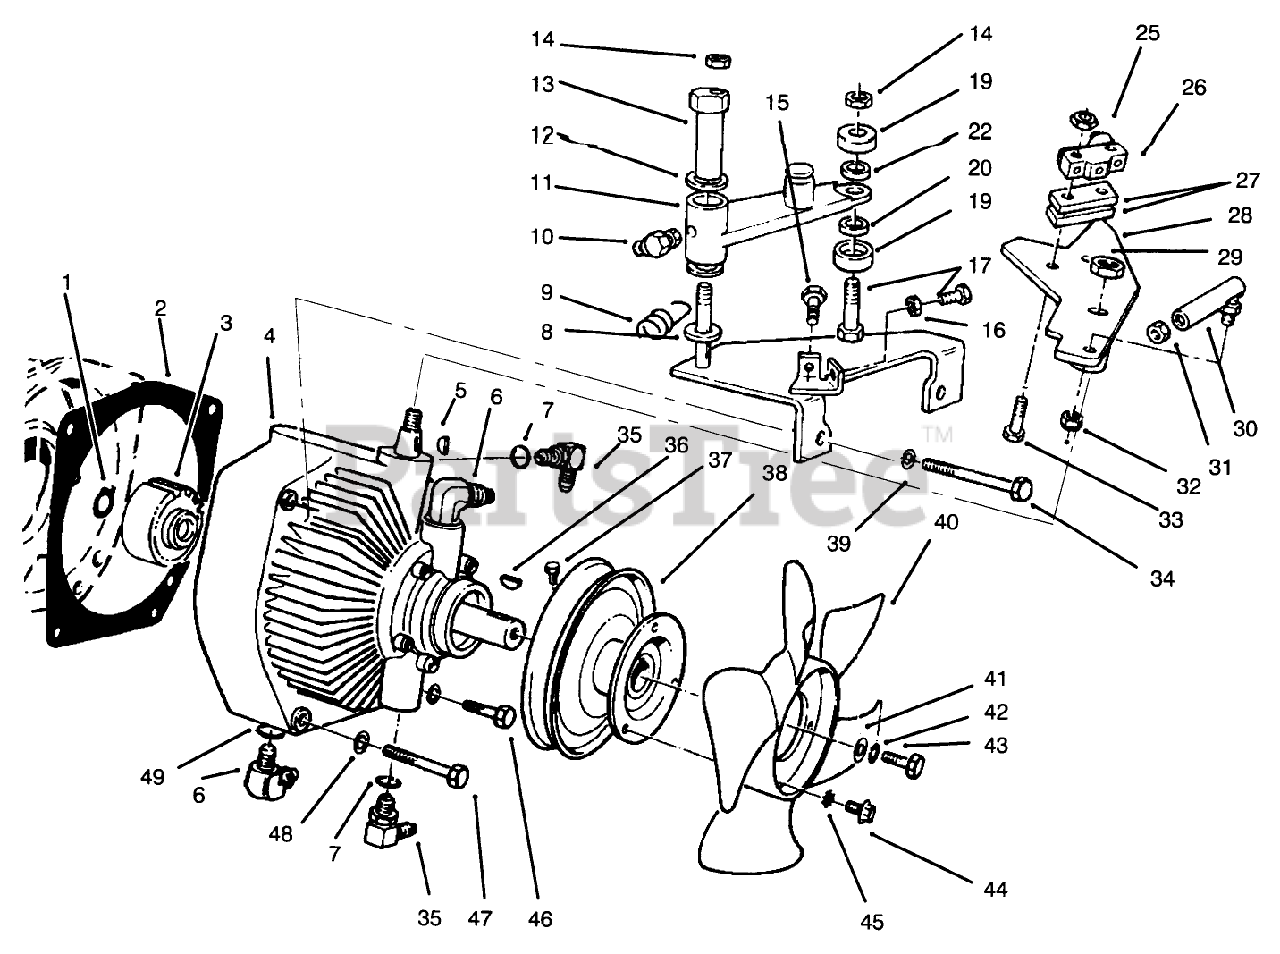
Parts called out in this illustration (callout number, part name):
1	RING-SNAP, EXTERNAL
2	TRANS GASKET
3	GEAR-SPUR
4	HYDROSTATIC TRANS.
5	KEY-WOODRUFF
6	Fitting-Hydraulic 90deg. (Incl. Ref. #49)
7	O-RING
8	WASHER-FLAT
9	SPRING-EXTENSION
10	FITTING-GREASE
11	NEUTRAL SWITCH ARM ASSY
12	WASHER-THRUST
13	STUD-TRACTION
14	NUT-LOCK, NI
15	SCREW-HH
16	NUT-HEX
17	SCREW-HH
19	BEARING-BALL
20	SPACER
22	SPACER-BEARING
25	NUT-HEX
26	SWITCH-MICRO
27	PLATE-SWITCH
28	Lever-Traction
29	NUT-LOCK, NI
30	JOINT-BALL
31	NUT-JAM
32	NUT-LOCK
33	SCREW-PPH
34	SCREW-HH
35	Fitting-Hydraulic 90deg. (Incl. Ref. #7)
36	KEY-WOODRUFF
37	SCREW-SQH
38	TRANS PULLEY
39	WASHER-LOCK
40	FAN 8"
41	WASHER-FLAT
42	WASHER-LOCK
43	SCREW-HH
44	SCREW-SHWH
45	WASHER-LOCK/EXT
46	SCREW-HH
47	SCREW-HH
48	WASHER-LOCK
49	O-RING
